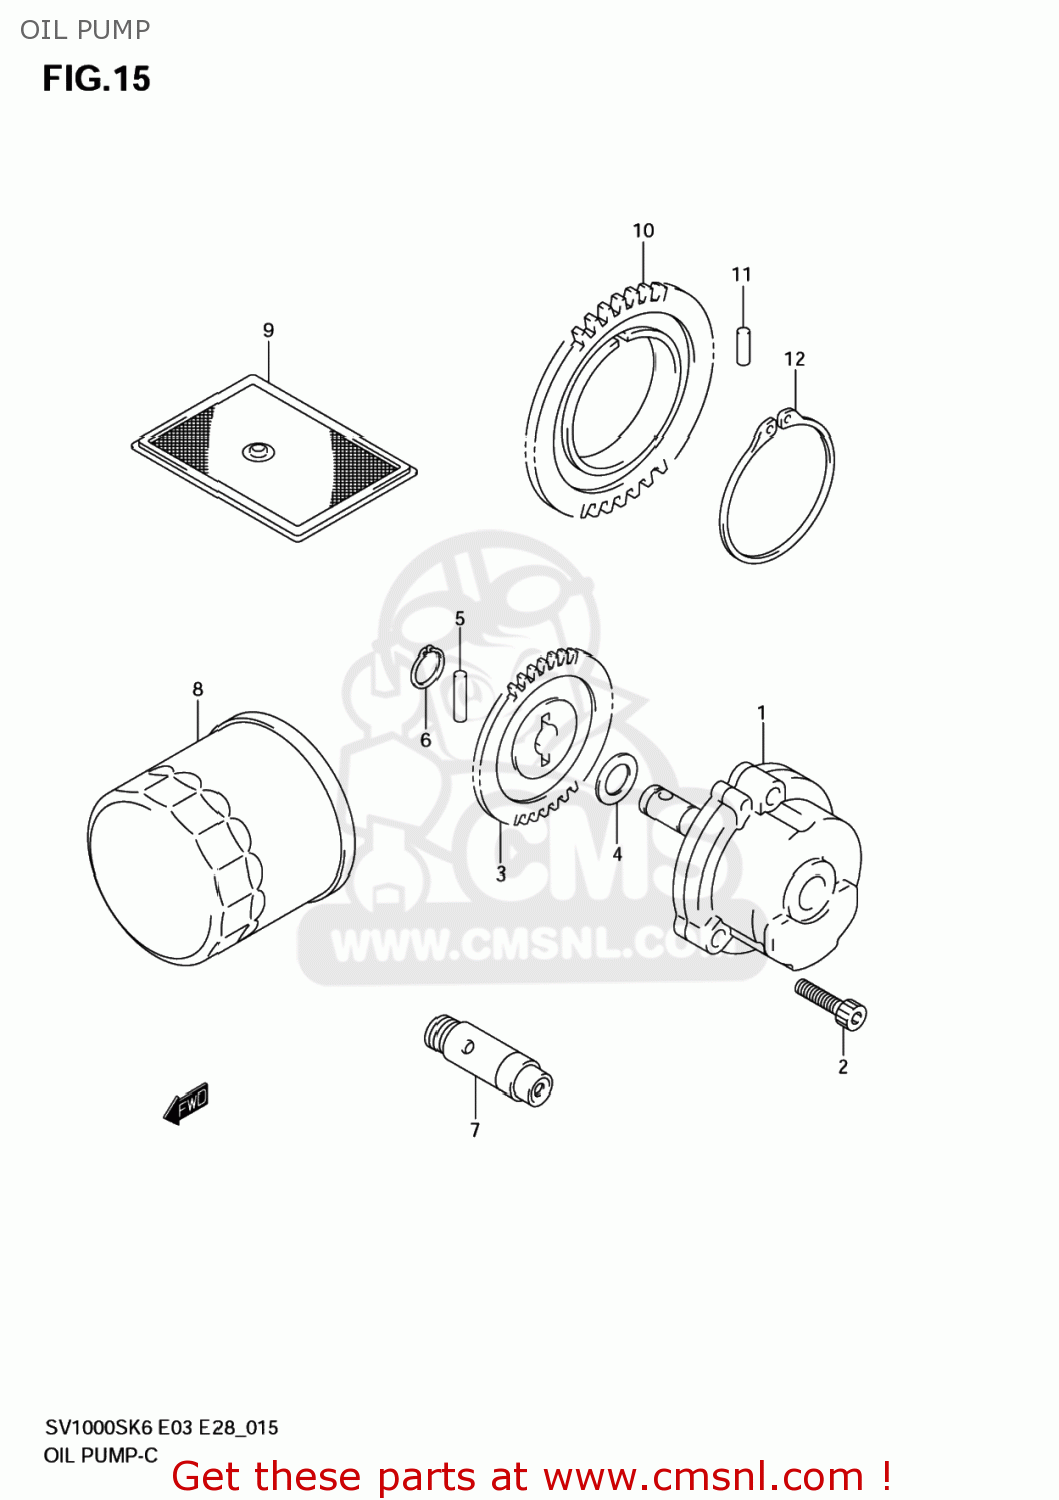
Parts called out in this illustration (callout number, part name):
1	PUMP ASSY,ENGINE OIL
2	BOLT,CL.COVER
3	GEAR,OIL PUMP DRIVEN
4	SHIM(10X18X0.5)
5	PIN(4X15.8)
6	CIRCLIP,10MM
7	VALVE ASSY,OIL RELIEF(7K)
8	FILTER ASSY,EN
9	STRAINER,ENGINE OIL
10	GEAR,ENG OIL PUMP DRIVE
11	PIN(6X6)
12	CIRCLIP
